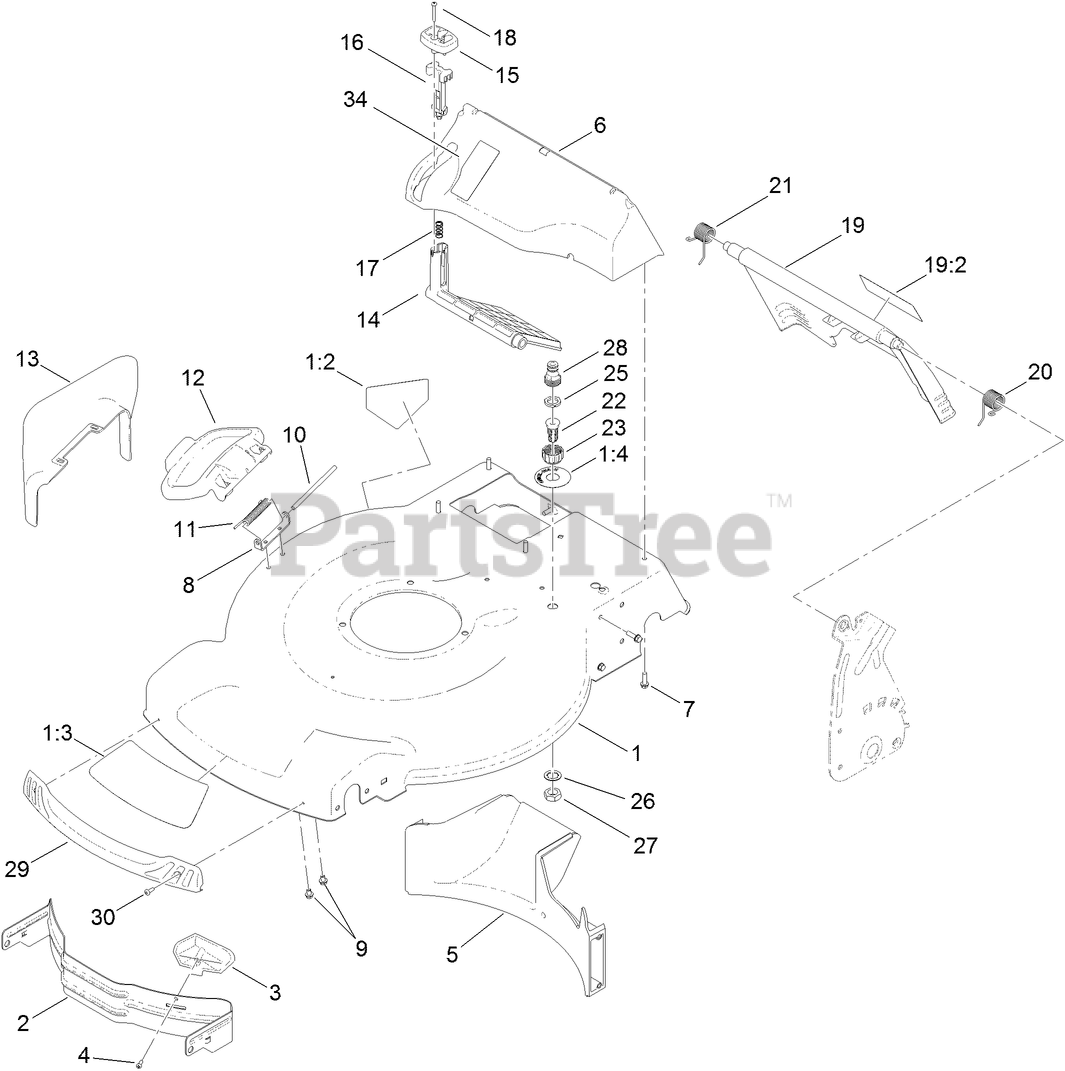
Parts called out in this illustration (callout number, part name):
1:2	DECAL-DANGER
1:4	DECAL-PORT, WASHOUT
2	BAFFLE-FRONT
3	KICKER-FRONT
4	SCREW-PPH
5	BAFFLE-REAR
6	CHUTE-RECYCLE
7	SCREW-HWH
8	BRACKET-COVER
9	SCREW-HWH
11	SPRING-TORSION
12	DEFLECTOR-SIDE
13	CHUTE-DISCHARGE, SIDE
14	DEFLECTOR-RECYCLE
15	KNOB-RECYCLE
16	LATCH-RECYCLE
17	SPRING-COMPRESSION
18	SCREW-PPH
19:2	DECAL-WARNING
20	SPRING-TORSION
21	SPRING-TORSION
22	PORT-WASHOUT
23	COUPLING-HOSE, WASHOUT PORT
25	WASHER-SEAL, WASHOUT PORT
26	WASHER-LOCK
27	NUT-JAM
28	ADAPTER-CONNECT, QUICK
29	BUMPER
30	SCREW-FORMING, THREAD
34	DECAL-BAG ON DEMAND
